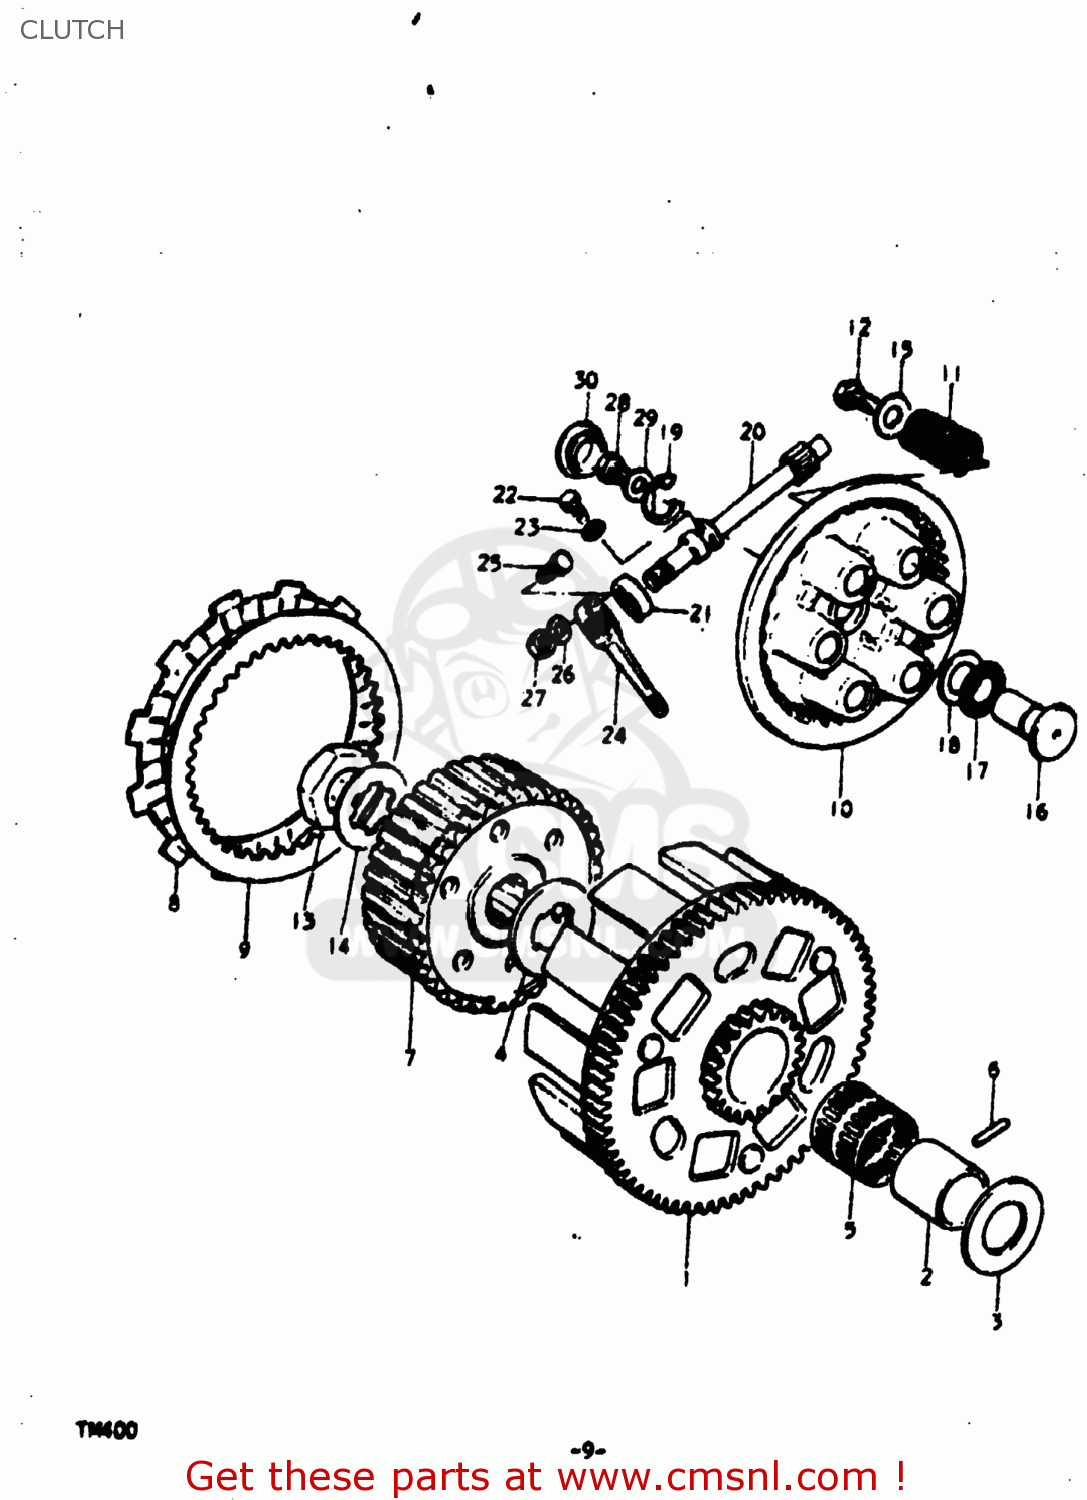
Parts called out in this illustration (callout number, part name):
1	GEAR ASSEMBLY,PRIMARY DRIVE
2	SPACER
3	WASHER
4	WASHER
5	BEARING
6	PIN
7	HUB,CLUTCH SLEEVE
8	PLATE,CLUTCH DRIVE (MCA)
9	PLATE,CLUTCH DRIVEN(T:2.0) (NAS)
10	DISC,CLUTCH PRESSURE
11	SPRING
12	BOLT
13	NUT
14	WASHER,LOCK
15	WASHER
16	RACK,CLUTCH RELEASE
17	BEARING(15X28X2)
18	WASHER
19	E RING 12MM
20	PINION,CLUTCH RELEASE
21	OIL SEAL
22	BOLT(6X12)
23	WASHER
24	ARM,CLUTCH RELEASE
25	BOLT
26	WASHER
27	NUT
28	BOLT
29	GASKET
30	GROMMET
